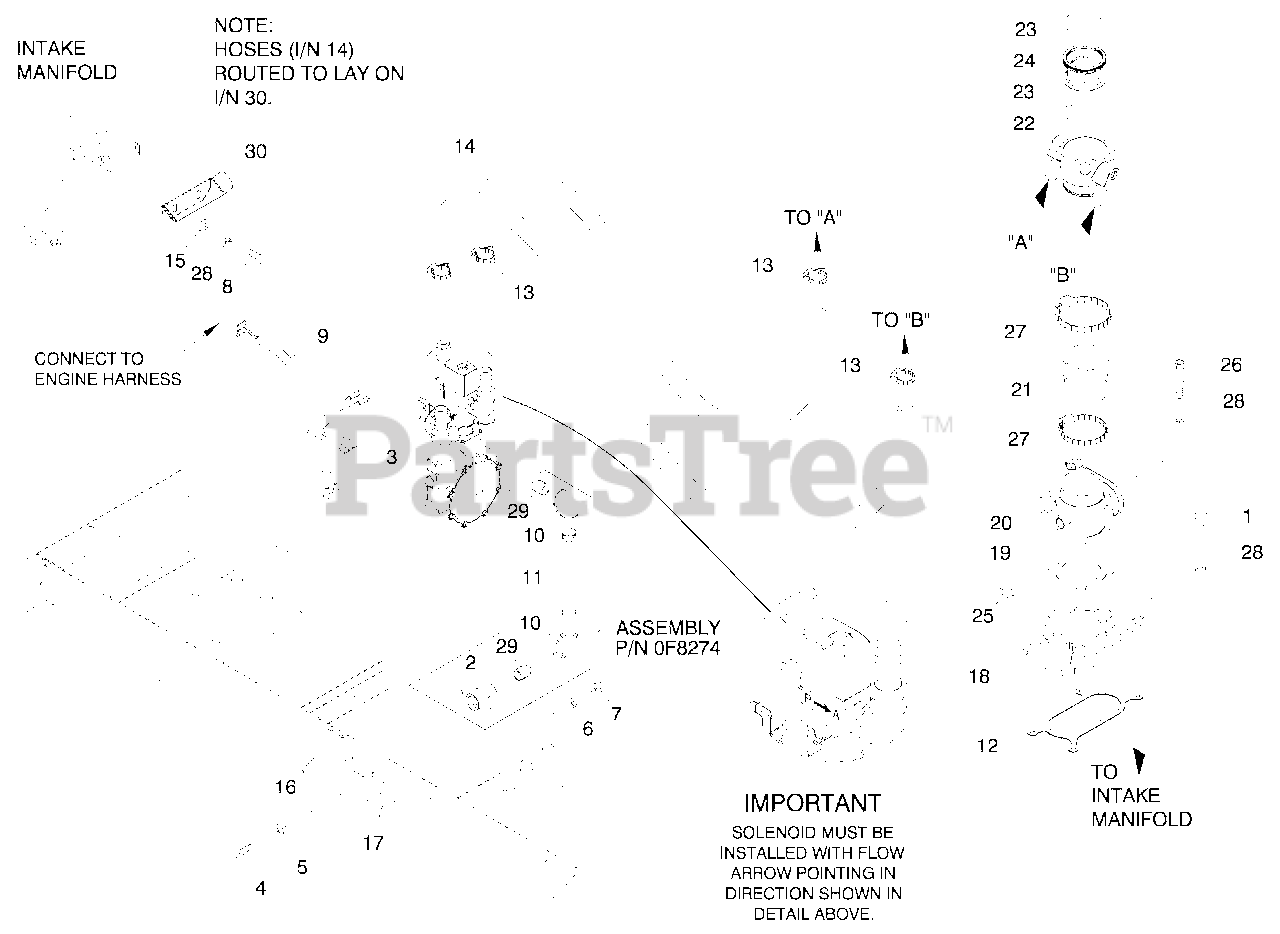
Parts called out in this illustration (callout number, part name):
1	SCREW HHC M6-1.0 X 35 G8.8 BLK
2	FLANGE FUEL INLET
3	REG ASSY 6.8L 70KW LPV CPL
4	SCREW HHC M8-1.25X 20 G8.8
5	WASHER FLAT 5/16-M8 ZINC
6	WASHER LOCK M8-5/16
7	NUT HEX M8-1.25 G8 CLEAR ZINC
8	SCREW HHC M6-1.0X 20 G8.8
9	HARNESS,FUEL JUMPER SINGLE REG
10	ELBOW 90D 3/4NPT
11	NIPPLE PIPE 3/4NPT X 7
12	GASKET ADAPTER THROT BODY
13	CLAMP HOSE #10 .56-1.06
14	HOSE 3/4 ID SAE-30R2 (38.5" LG)
15	WASHER FLAT M6
16	DECAL INLET PRESSURE
17	DECAL FUEL INLET NG (NATURAL GAS APPLICATION)
18	ASSY,ADAPTER,THROTTLE BODY
19	GASKET, GOVERNOR ACTUATOR
20	ACTUATOR BOSCH 60, GOVERNOR
21	REDUCER 3.0" TO 2.75" TURBO
22	MIXER, 40/60MM ACTUATOR ASSY
23	O-RING 2-3/4X3/32X2-15/16
24	VENTURI, THROTTLE 36MM
25	PLUG STD PIPE 1/4 STEEL SQ HD
26	SCREW SHC M6-1.0 X 50 C8.8
27	CLAMP HOSE #44 2.31-3.25
28	WASHER LOCK M6-1/4
29	NIPPLE CLOSE 3/4X1.375
30	BRACKET, HOSE RISER
